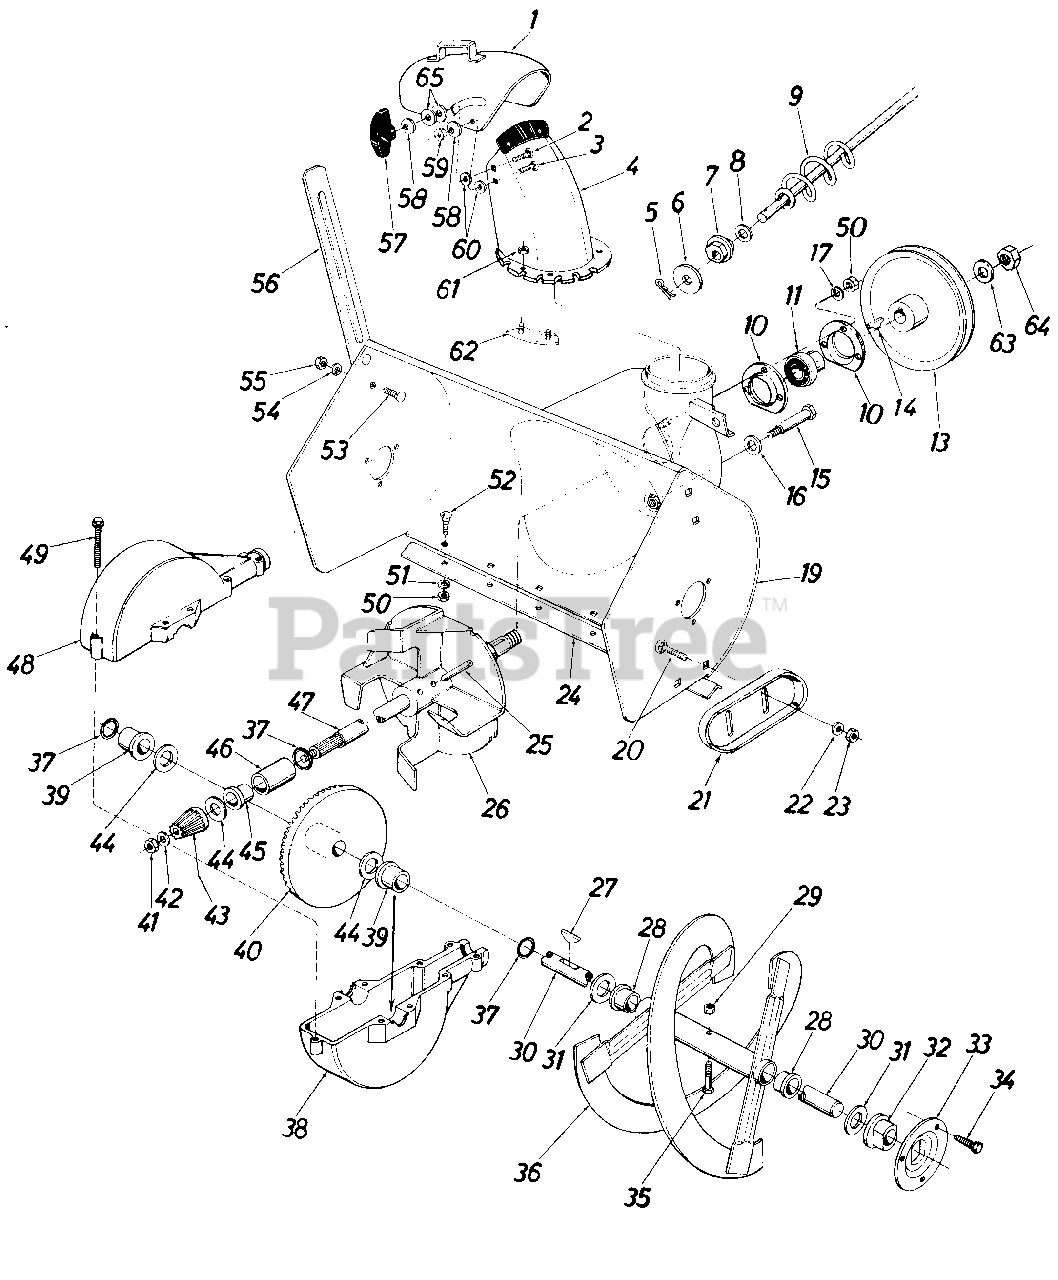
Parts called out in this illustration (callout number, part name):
1	Top Chute Ass'y.
2	Carriage Bolt 5/16-18 x 1.00" Lg.*
3	Carriage Bolt 5/16-18 x .62" Lg.*
4	Chute Ass'y.
5	Cotter Pin
6	Fl-Wash. .390 I.D. x 1.50"O.D.
7	Hex Bushing
8	Fl-Wash .385 I.D. x .62" O.D.
9	Chute Crank Ass'y.
10	Bearing Housing
11	Self-Align Brg. w/Collar.75" I.D.
13	1/2" "V"-Pulley .625" I.D. x 7.50" O.D.
14	#61 Hi-Pro Key 3/16" x 5/8" Dia.
15	Shld. Bolt .50" Dia. x 2.11" Lg.
16	Bell-Wash. .40" I.D. x .88" O.D. x .06
17	L-Wash. 5116" I.D.*
19	20" Blower Housing Ass'y.
20	Carriage Bolt 3/8-16 x .62" Lg . *
21	Slide Shoe
22	Bell-Wash. 3/8" I.D.
23	Hex Jam Nut 3/8-16 Thd.
24	20" Shave Plate
26	11" Dia. Blower Fan Ass'y.
27	#9 Hi-Pro Key 3/16 x 3/4" Dia.
28	Flange Brg. .75" I.D. x .88" O.D. x .62
29	Hex Ins. L-Nut 5/16-18
30	Spiral Axle
31	Fl-Wash. .75" I.D. x 1.50" O.D. x .06
32	Flange Brg. w/Flats .755" I .D.
33	Bearing Housing
34	Hex Wash. Hd. Self-Tap Scr. 5/16-24 x .50" Lg.
35	Hex Bolt 5/16-18 x 1.50" Lg.
36	20" Spiral Ass'y.-L.H.
37	"O"-Ring-3/4" I.D.
38	Bevel Gear Housing-Lower Half
39	Plastic Flange Brg. .755" I.D.
40	Bevel Gear
41	Hex Cent. L-Nut 5/16-24 Thd.
42	Fl-Wash. .34" I.D. x .62" O.D. x .06
43	Pinion Gear
44	Fl-Wash. .75" I.D. x 1.25" O.D. x .06
45	Flange Brg. .755" I.D.
46	Sleeve Brg. .755" I.D.
47	Blower Axle
48	Bevel Gear Housing-Upper Half
49	Hex Wash. Hd. Self-Tap Scr. 1/4-20 x 1.00" Lg .
50	Hex Nut 5/16-18 Thd.*
51	Bell-Wash. .34" I.D. x .88" O.D.
52	Carriage Bolt 5/16-18 x .62" Lg.*
53	Carriage Bolt 5/16-18 x .62" Lg.*
54	L-Wash. 5/16" I.D.*
55	Hex Nut 5/16-18 Thd.*
56	Drift Cutter Bart
57	Knob
58	Bell-Wash. .34" I.D. x .88" O.D.
59	Hex Cent. L-Nut 5/16-18 Thd.
60	Fl-Wash. .53" I.D. x 1.25" O.D. x .100
61	Hex Cent. L-Nut 1/4-20 Thd.
62	Chute Flange Keeper Ass'y.
63	Fl-Wash. .64" I.D. x .94" O.D. x .06
64	Hex Jam Nut 5/8-18 Thd.
65	Fl-Wash. .344 I.D. x 1.125 O.D.
